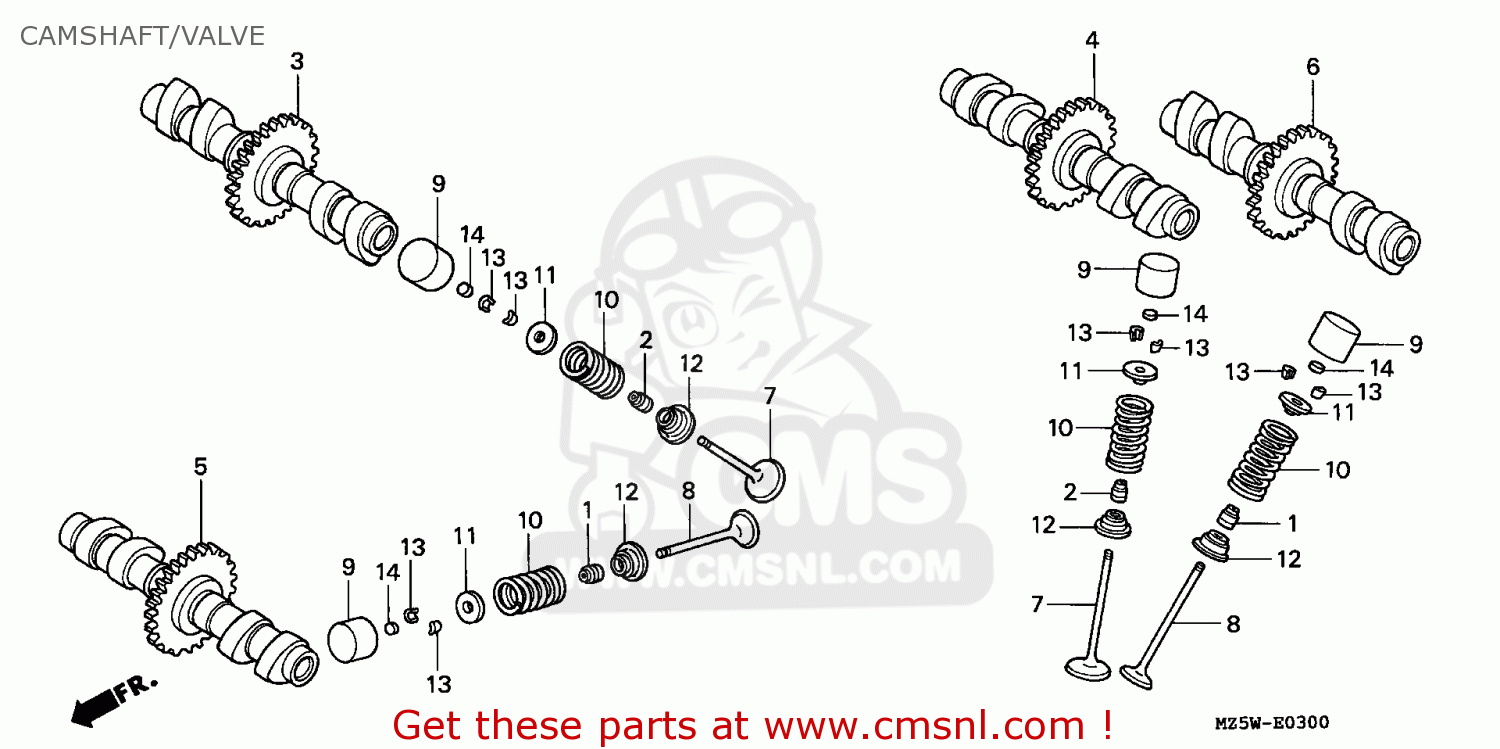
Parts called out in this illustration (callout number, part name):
1	SEAL,EX.VALVE STE
2	SEAL,VALVE STEM
3	CAM SHAFT COMP,FR
4	CAM SHAFT COMP,RR
5	CAM SHAFT COMP,FR
6	CAM SHAFT COMP,RR
7	VALVE,INLET
8	VALVE,EXHAUST
9	LIFTER,VALVE
10	SPRING,VALVE
11	RETAINER,VALVE SP
12	SEAT, VALVE SPRING
13	COTTER,VALVE
14	SHIM,TAPPET (1.20
